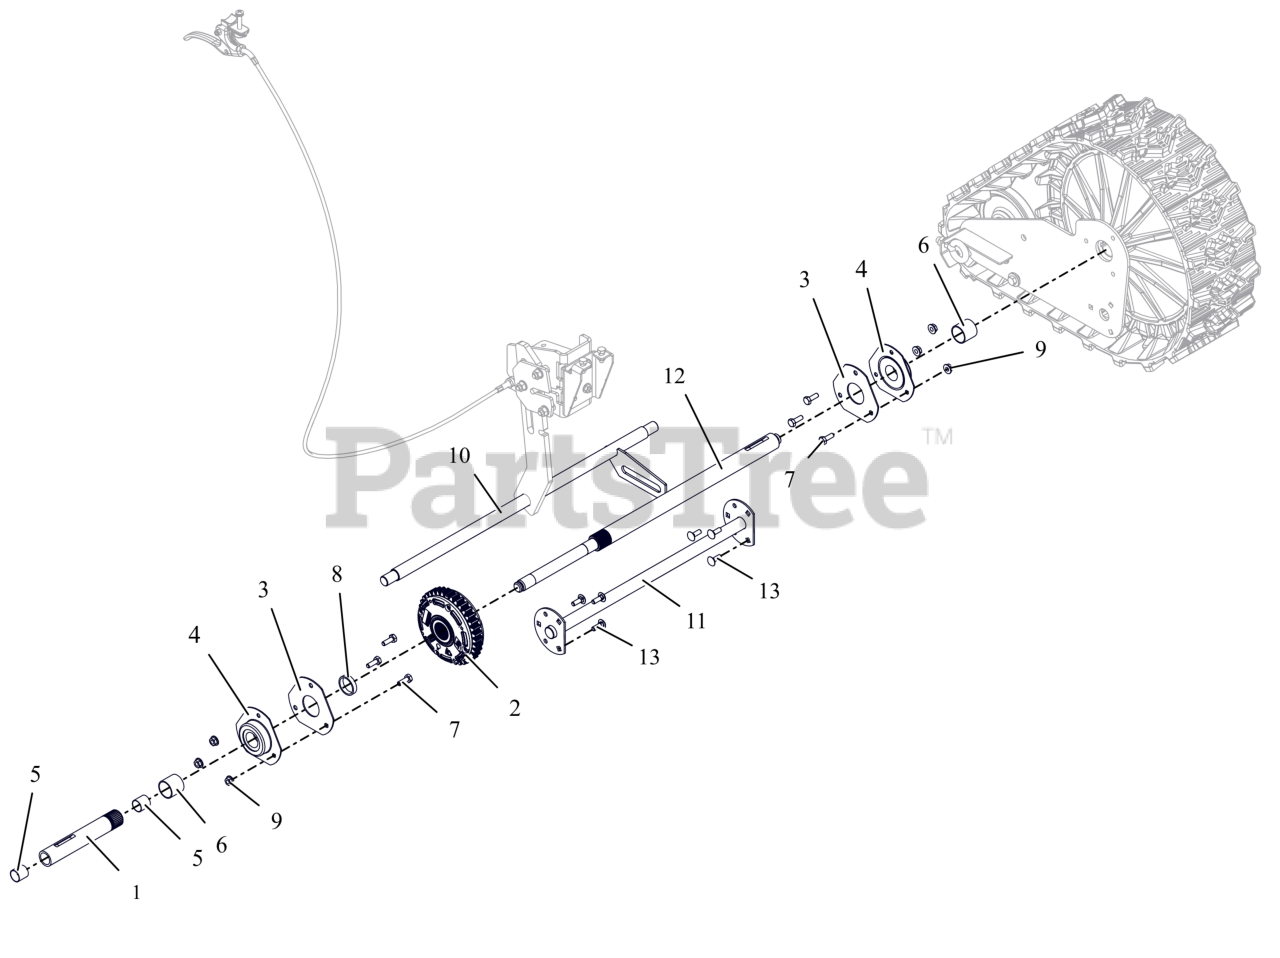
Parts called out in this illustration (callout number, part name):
1	AXLE, SHORT-W/BUSHINGS
2	DIFFERENTIAL, AUTOMATIC
3	PLATE, BEARING SPACER
4	BRG-FLG 1.003/1.000 3 BOLT
5	BSHG-SLV .706X.764X.75 BRZ
6	BSHG-SLV, 1.012X1.125X1.00
7	BLT, HEX .25-20X.75 G5 ZCC
8	BSHG, SLV 1.062X1.228X.268
9	NUT-LK-CTR-FLG .25-20 ZC120
10	AXLE, REAR-BWT WLDMT
11	SUPPORT, FRONT-BWT
12	AXLE, LONG-TRACK DIFFERENTIAL
13	BLT, RHSN .25-20X.750 G5 ZCC
